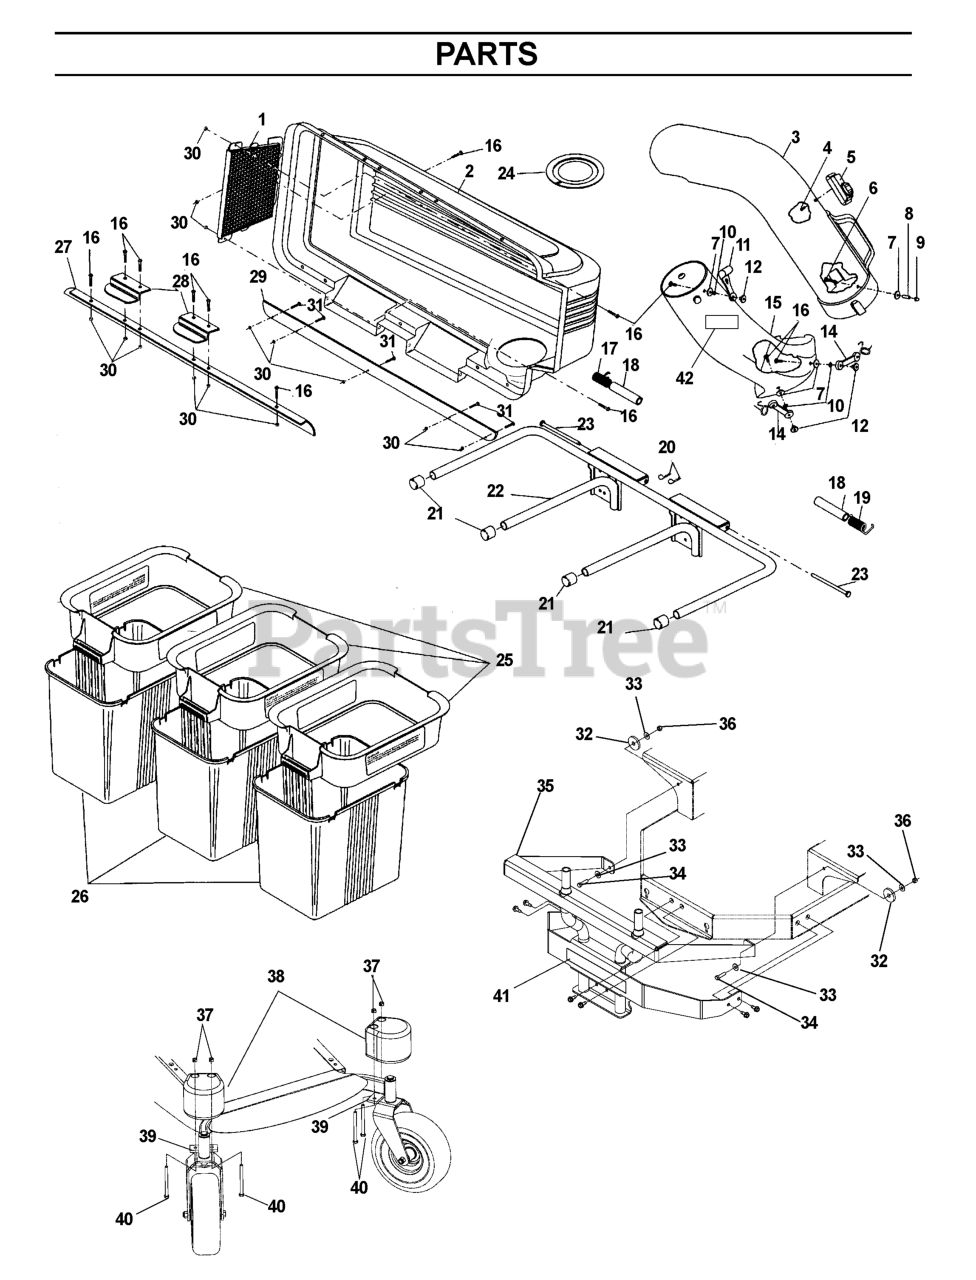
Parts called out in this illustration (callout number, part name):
1	COVER SCREEN
2	COVER BAGGER
3	CHUTE.BAGGER.UPPER.48
5	INDICATOR DUMP BAG
6	SCREW
9	NUT
10	LOCKWASHER #10
11	LATCH.HOOD.
12	WELDNUT
14	LATCH ASSY
15	CHUTE.BAGGER.LOWER.48"
16	SCREW
17	SPRING COVER LH
18	SPACER BAG 3-PIN
19	SPRING COVER RH
20	RETAINER SPRING
21	PLUG, TUBING END
22	BAGGER.ASM.FRAME.3BIN.BLACK
23	HINGE PIN
24	GASKET.COVER.BAGGER
25	CONTAINER TOP
26	CONTAINER BOTTOM
27	BAGGER TOP SEAL
28	LATCH CER38
29	STRIP.REINFORCEMENT.3.BIN.
31	Screw, #10-24 x 1/2
32	SPINDLE WASHER
33	WASHER 5/16 FLAT
34	HCS 5/16C X 1 1/4
36	NUT 5/16 NYLOC
37	NUT 3/8C CENTERBLOCK
38	WHEEL WEIGHT
39	BLACK STRAP
40	HCS 3/8C X 4 1/2
41	DECAL, HUSQVARNA 12"
42	DECAL, CATCHER
532104419	REPL BY 532 10 50-70
